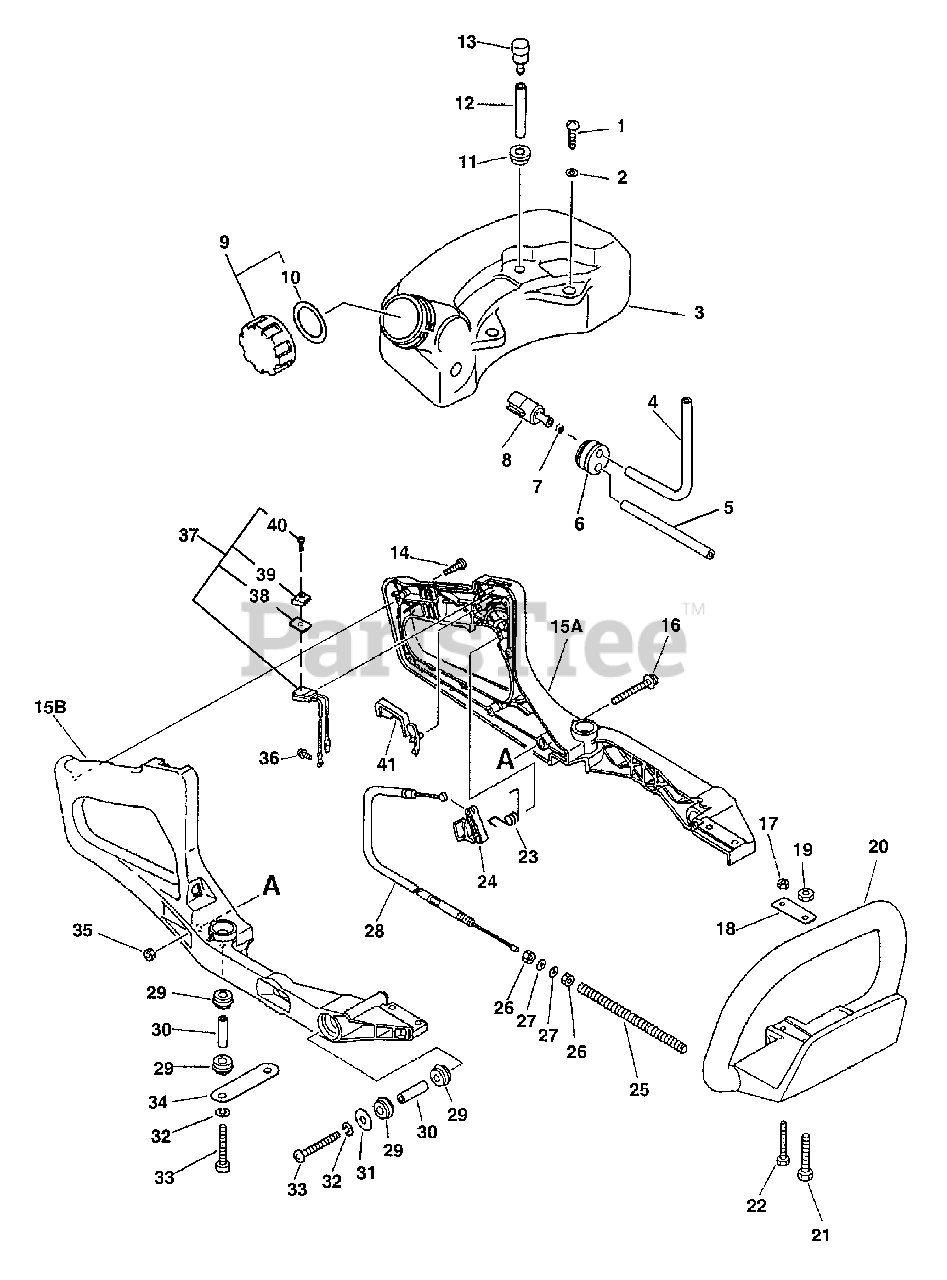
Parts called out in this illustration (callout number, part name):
1	SCREW 5×16
2	WASHER 5.5×12×0.8
3	TANK, FUEL
4	PIPE, FUEL
5	PIPE, FUEL RETURN 3×6×110
6	GROMMET, FUEL
7	CLIP 6 MM
8	FILTER, FUEL
9	CAP ASSY, FUEL
10	GASKET, FUEL CAP
11	GROMMET
12	PIPE, FUEL
13	VENT ASSY
14	SCREW 4×25
15A	HANDLE, REAR - LEFT
15B	HANDLE, REAR - RIGHT
16	SCREW 5×64
17	NUT M5
18	PLATE, EYE
19	NUT, HEX M6
20	HANDLE, SUPPORT
21	BOLT - 6×32
22	BOLT 5×35 SP
23	SPRING, TORSION
24	TRIGGER, THROTTLE
27	WASHER 6.5×11.5×0.8
28	CABLE, THROTTLE
30	SPACER
32	WASHER, SPRING 5
33	SCREW 5×40
34	PLATE, EYE
35	NUT M5
36	SCREW 5×10
37	IGNITION SWITCH ASSY
38	LABEL, SWITCH
39	KNOB, SWITCH - ORANGE
40	SCREW 3×10
41	LOCKOUT, THROTTLE
